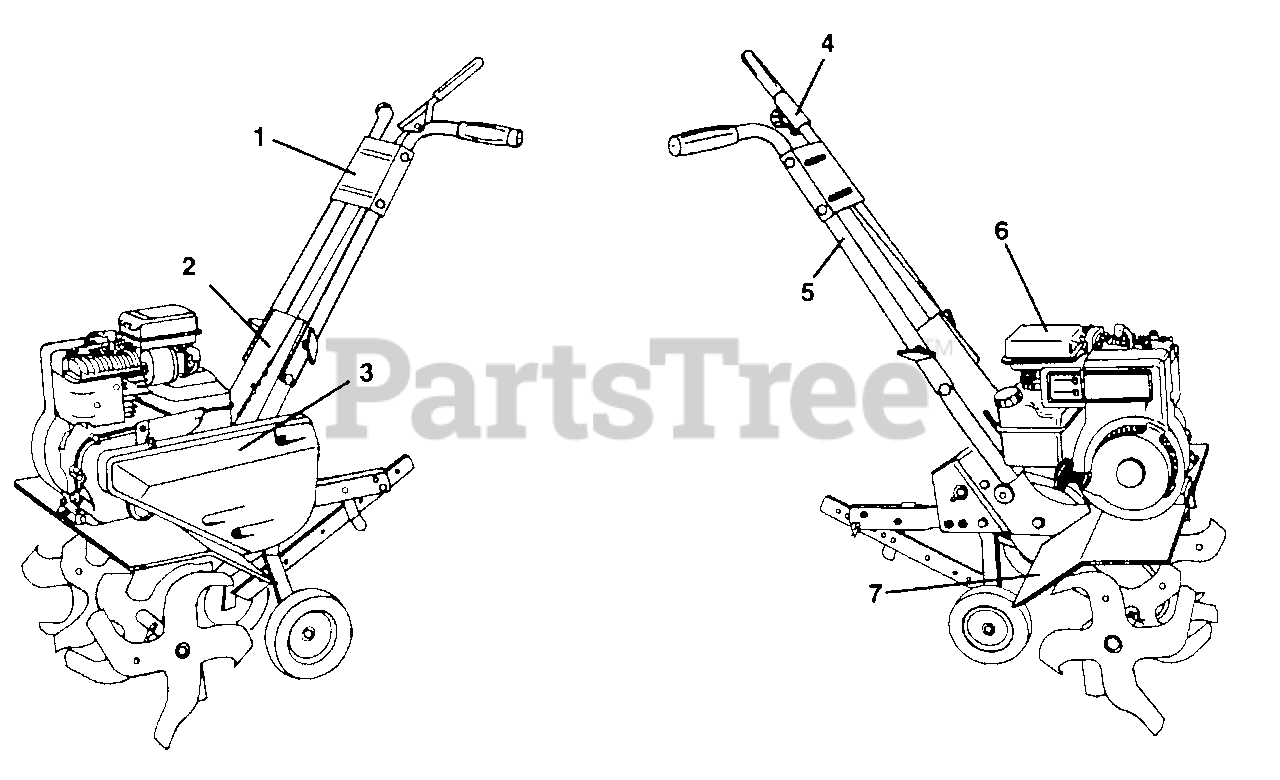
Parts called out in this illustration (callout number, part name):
1	Decal, Logo
2	Decal, HP (AYP part number)
3	Decal, Logo (AYP part number)
4	Decal, Tine Control (AYP part number)
5	Decal, Hand Placement (AYP part number)
6	Decal, Caution (AYP part number)
7	Decal, Warning, Rotating Tines (AYP part number)
